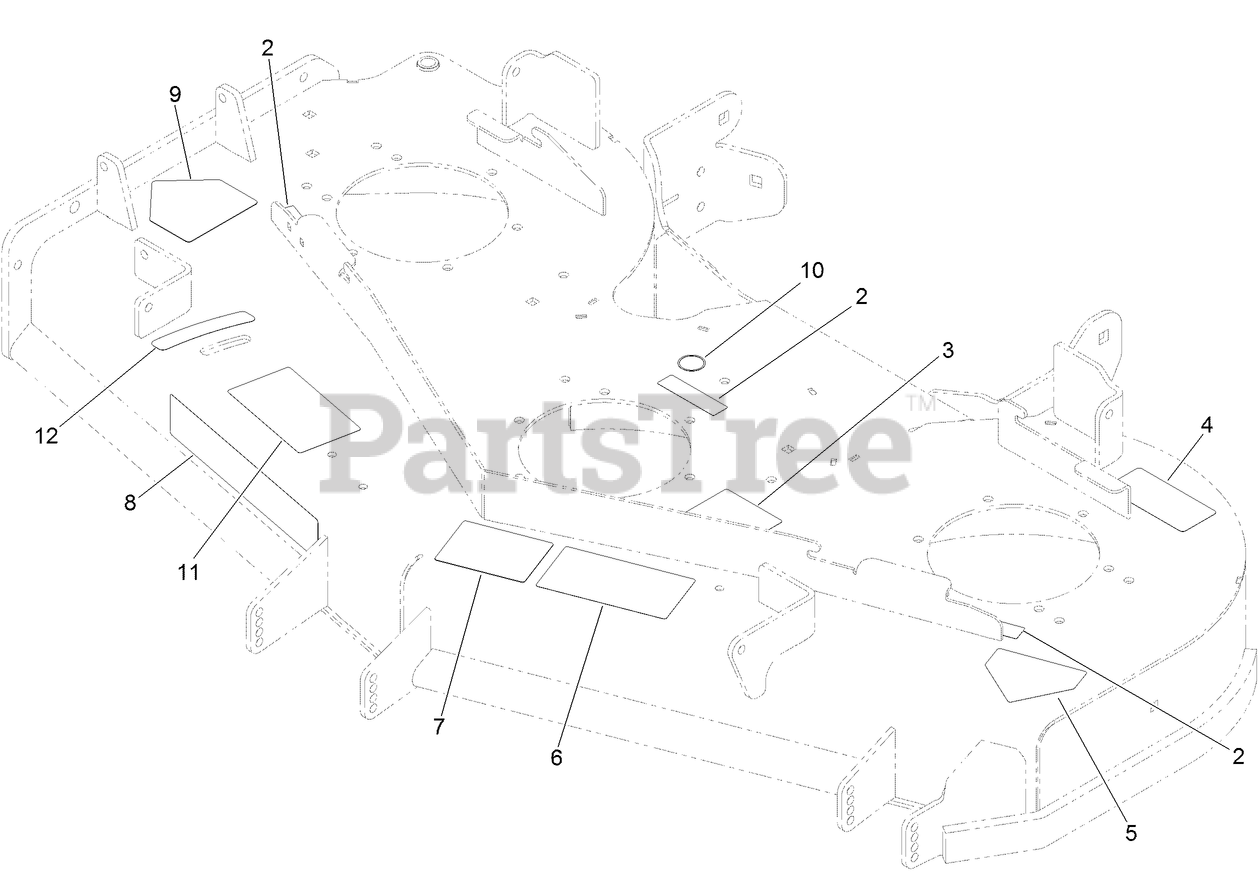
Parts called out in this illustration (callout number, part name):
2	DECAL-COVER, MISSING
3	DECAL-ROUTING, DECK BELT
4	DECAL-TORQUE
5	DECAL-DANGER
6	DECAL-DANGER, THROWN OBJECT
7	DECAL-SCALP, ANTI
9	DECAL-DANGER
10	DECAL-GREASE
11	DECAL-ADJUSTMENT, BAFFLE
12	DECAL-SETTING, BAFFLE
